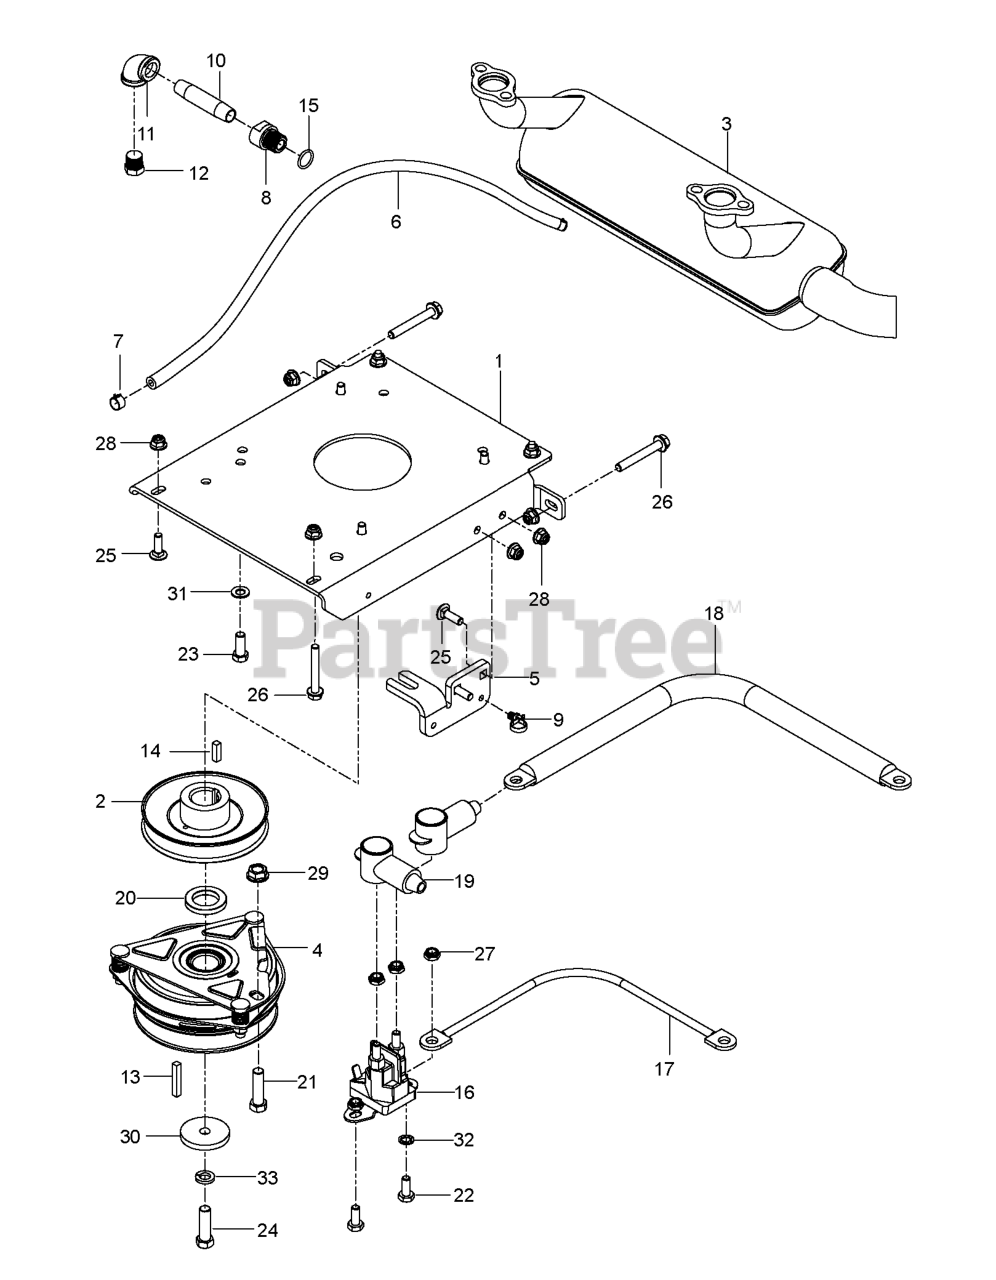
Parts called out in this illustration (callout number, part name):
1	PLATE.ENGINE.BLACK
2	PULLEY, ENGINE
3	MUFFLER.26HP.KAW.FX651V-730V
4	CLUTCH, 150 FT/LBS
5	STOP, CLUTCH, OGURA
6	FUEL LINE 18"
7	HOSE CLAMP
8	ADAPTER, OIL DRAIN
9	TIE WRAP, 8-3/8", W/CLIP
10	PIPE NIPPLE 3/8 X 3
11	90 DEG.ELBOW 3/8NPT
12	PLUG, DRAIN 3/8 NPTF
13	KEY 1/4 SQ X 2
14	KEY 1/4 SQ X 1.0
17	GROUND WIRE (KAW)
18	CABLE POSITIVE
20	SPACER, .25 X 1.135 I.D.
21	HCS 7/16-14 X 1-1/4 GR 5 ZD
22	HCS 1/4C X 5/8
23	HCS 3/8-16X1.GRD.5.ZD
24	HCS 7/16F X 1 1/2
25	RHSNB 5/16C X 1
26	HHFS 5/16-18 X 2.25 GD 5
27	JAM NUT 1/4C (2 2 PW01)
28	5/16-18 NYLOC FLANGE NUT
29	NUT 7/16C WHIZ
30	BLADE WASHER
31	WASHER, 3/8 DISC SPRING SPEC
32	WASHER 1/4 INT TOOTH
33	WASHER 7/16 LOCK
